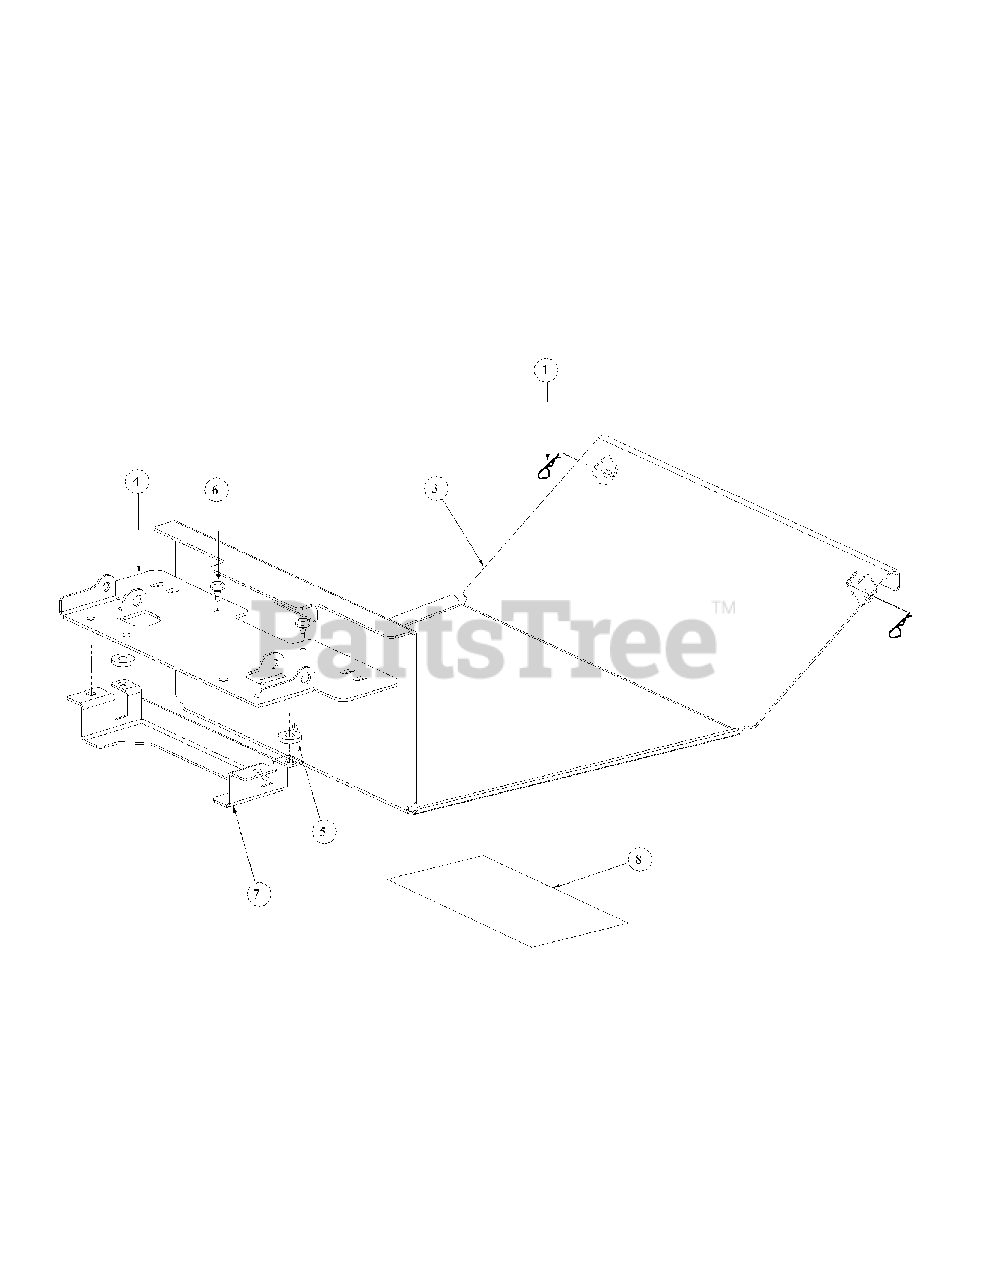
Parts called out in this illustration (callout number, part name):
1	Hair Pin, 3/8-1/2
3	Floor Panel Assembly
5	Washer
6	Rubber Bumper, .62 OD x .22 Thick
7	Support, Seat Bracket
8	Label, Belt Routing and Lubrication
